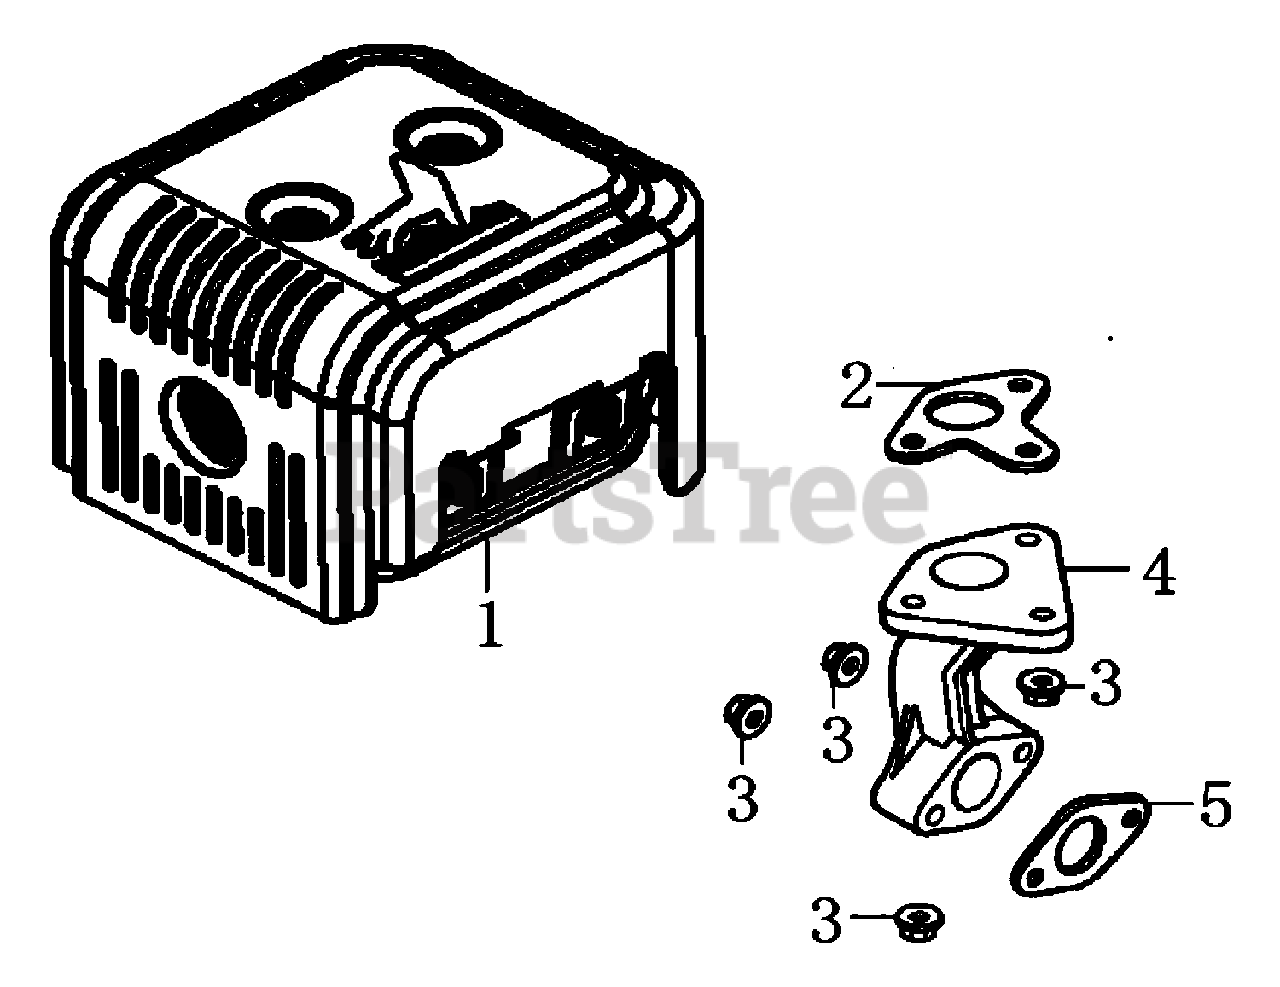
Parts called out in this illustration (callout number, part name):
1	MUFFLER ASSY.
2	GASKET, EXH. PIPE
3	NUT, HUX., M8
4	MANIFOLD, EXHAUST
5	GASKET, MUFFLER
